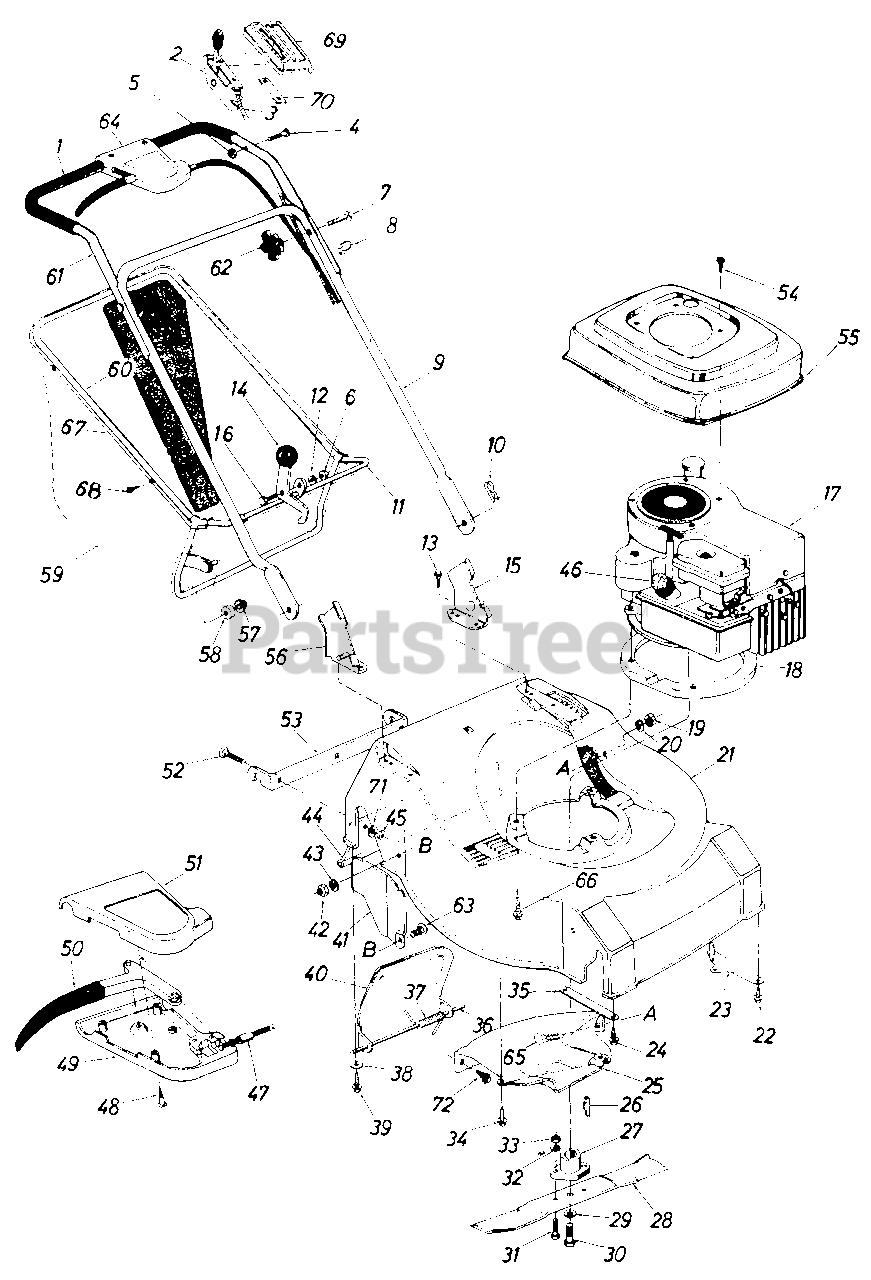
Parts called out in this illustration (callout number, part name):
2	Throttle Control Ass'y.
3	Conduit and Wire
4	Hex Bolt 1/4-20 x 1.50" Lg.
5	Hex Cent. L-Nut 1/4-20 Thd.
6	Hex Nut 5/16-18 Thd.
7	Curved Carriage Bolt 5/16-18 x 1.75" Lg.
8	Cable Tie
9	Lower Handle
10	Internal Cotter Pin 5/16" Dia.
11	Grass Catcher Lower Frame Ass'y.
12	L-Wash. 5/16" I.D.
13	Hex Wash. Hd. B-Tap Scr. 1/4 x 1.00" Lg.
14	Cam Lever Grip Ass'y.
15	Handle Brkt. Ass'y. L.H.
16	Shld. Bolt .437 Dia. x .180
18	Engine Mount Cover
19	Hex Nut 1/4-20 Thd.
20	L-Wash. 1/4" I.D.
21	22" Rear Discharge Deck
22	Hex Wash. Hd. AB-Tap Scr. 1/4" x .62" Lg.
23	Left Strap
24	Hex Wash. Hd. AB-Tap Scr. 1/4" x .62" Lg.
25	Rear Baffle L.H.
26	#6 Hi-Pro Key 5/32 x 5/8 Dia.
27	Blade Adapter Kit
28	22" Blade
29	L-Wash. 3/8" I.D. - H.D.
30	Hex Bolt 3/8-24 x 1.50" Lg.
31	Hex Bolt 5/16-24 x 1.00" Lg.
32	L-Wash. 5/16" I.D.
33	Hex Nut 5/16-24 Thd.
34	Hex Wash. Hd. AB-Tap Scr. 1/4 x .62" Lg.
35	Right Strap
36	Rod .25" Dia. x 8.25 Lg.
37	Torsion Spring .46" O.D. x 2.38" Lg.
38	Fl-Wash. .281" I.D. x .625 O.D. x .052
39	Hex Wash. Hd. AB-Tap Scr. 1/4 x .62 Lg.
40	Chute Door
41	Side Baffle
42	Hex Nut 1/4-20 Thd.
43	L-Wash. 1/4" I.D.
44	Rear Flap Ass'y.
45	Hex L-Nut 1/4-20 Thd.
47	Clutch Control Cable
48	Fl. Cr. Sunk AB-Tap Scr. #10 x 1.0" Lg.
49	Rear Cover
50	Lever Clutch Control
51	Front Cover
52	Carriage Bolt 1/4-20 x .75" Lg.
53	Grass Catcher Hitch Brkt.
54	Hex AB-Tap Scr. #8 x .38" Lg.
56	Handle Brkt. Ass'y. R.H.
57	Cap Speed Nut 3/8" Rod
58	Plastic Roller
59	Grass Bag
60	Grass Catcher Upper Frame
61	Upper Handle
62	Hand Knob
63	Carriage Bolt 1/4-20 x .50" Lg.
64	Clutch Control Ass'y. Comp.
65	Carriage Bolt 1/4-20 x .50" Lg.
66	Hex Wash. Hd. Self-Tap Scr. 3/8-16 x .88" Lg.
67	Grass Catcher Top Cover
68	Hex AB-Tap Scr. #10 x 1/2" Lg.
69	Plastic Cover
70	Speed Nut #8-32 Twin Type
71	Fl-Wash. .281" I.D. x .734" O.D. x .063
72	Hex Wash. Hd. Drill Scr. 1/4" x .75" Lg.
